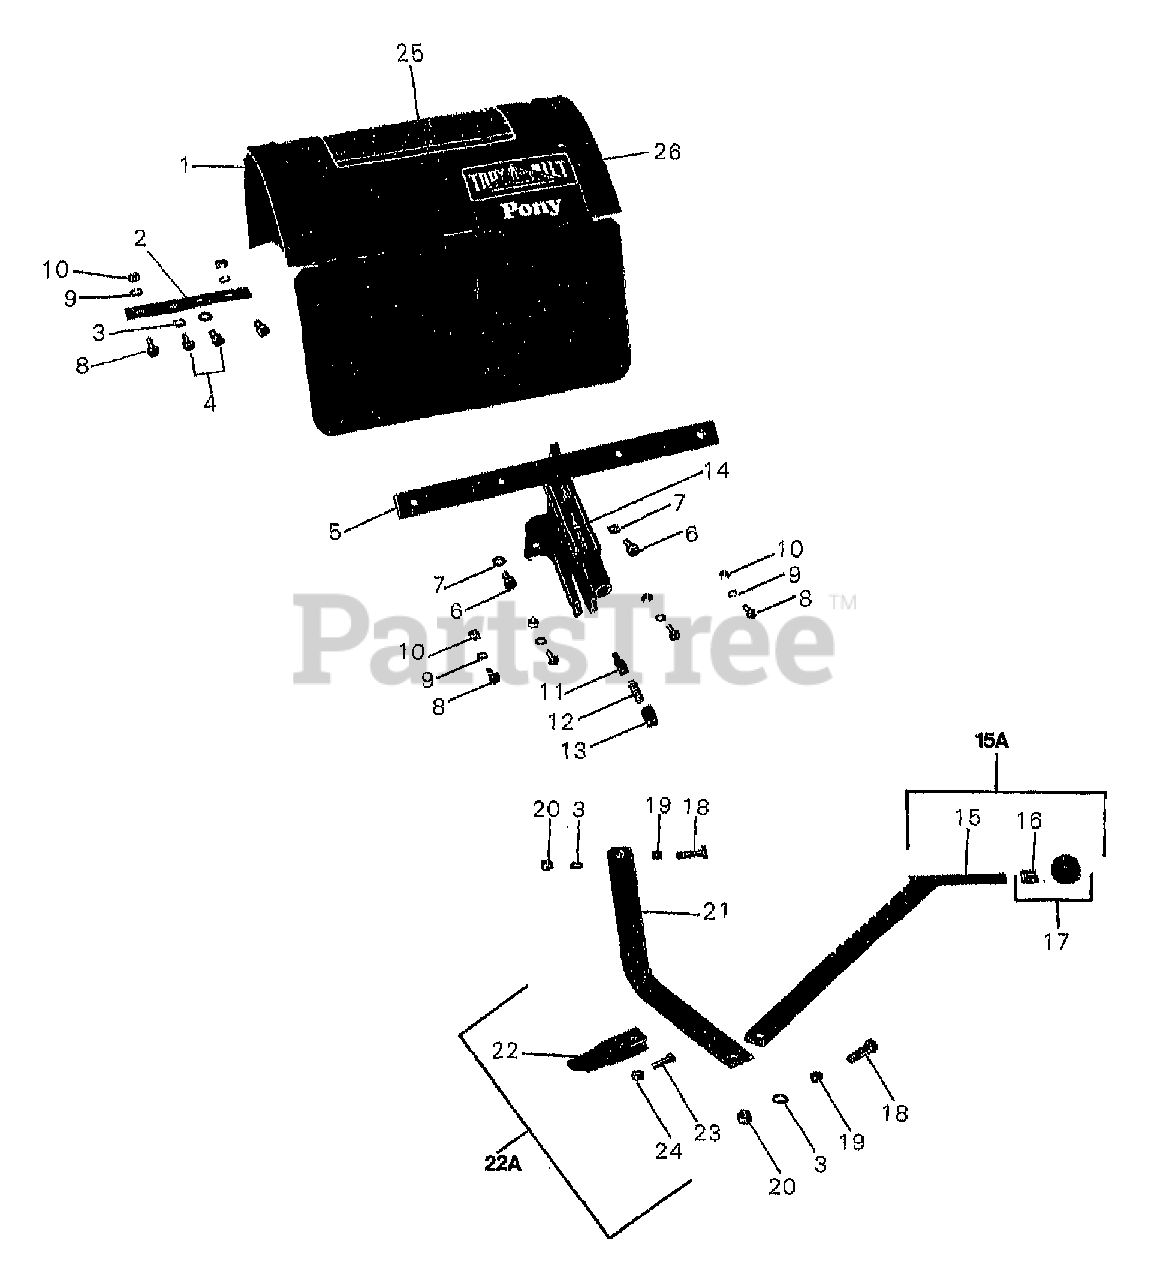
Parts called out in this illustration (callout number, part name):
1	HOOD W/DECAL-PONY 2 (INCL. 25 & 26)
1	HOOD W/DECALS (INCL. 25 & 26)
2	PLATE-HOOD MTG (REPLACES SHORTER VERSION USED ON P14465 & EARLIER)
3	WASHER-LK .375 @ DEPL
4	SCR-HH 3/8-16X1.0 G5 ZP
5	KIT-REAR HOOD BRKT PONY
6	SCR-HHC 5/16-18X.75 GR 5 (BRACKET TO REAR BEARING CAP)
7	WASHER-LK .312 ZP
8	SCR-RH 1/4-20 X .75 (HOOD TO BRACKET)
9	WASHER-LK .25 ZP
10	NUT-HEX 1/4-20 ZP
11	PLUNGER
12	SPRING .406 X 1.25
13	PLUG-PIPE 1/4 NPT
14	PIN-ROLL .25 X 1 (SPIRAL)
15	BAR - DEPTH ADJUSTMENT (NOT AVAIL. SEP.)
15A	DEPTH REGULATOR W/KNOB (INCL. 15-17)
16	RING-TOLERANCE .5325 ID
17	KNOB-CONTROL (INCL. RETAINING RING, #16)
18	SCR-HH 3/8-16X1.25
19	BUSHING-.5X.375X.3 (REPLACES 1113)
20	NUT-HEX 3/8-16 ZP
21	BAR-DRAG
22	SOD POINT
22A	SOD POINT ASSY - COMPLETE (INCL. #9811 LOCKNUT, #9701 BOLT, #1294 SOD POINT)
23	SCR-HH 1/4-20X.75 G5 ZP
24	NUT-LK 1/4-20
25	DECAL-HOOD TILLER OPERATION INSTRUCTIONS
26	DECAL-HOOD LOGO PONY OPC (MODEL NAME DECAL)
